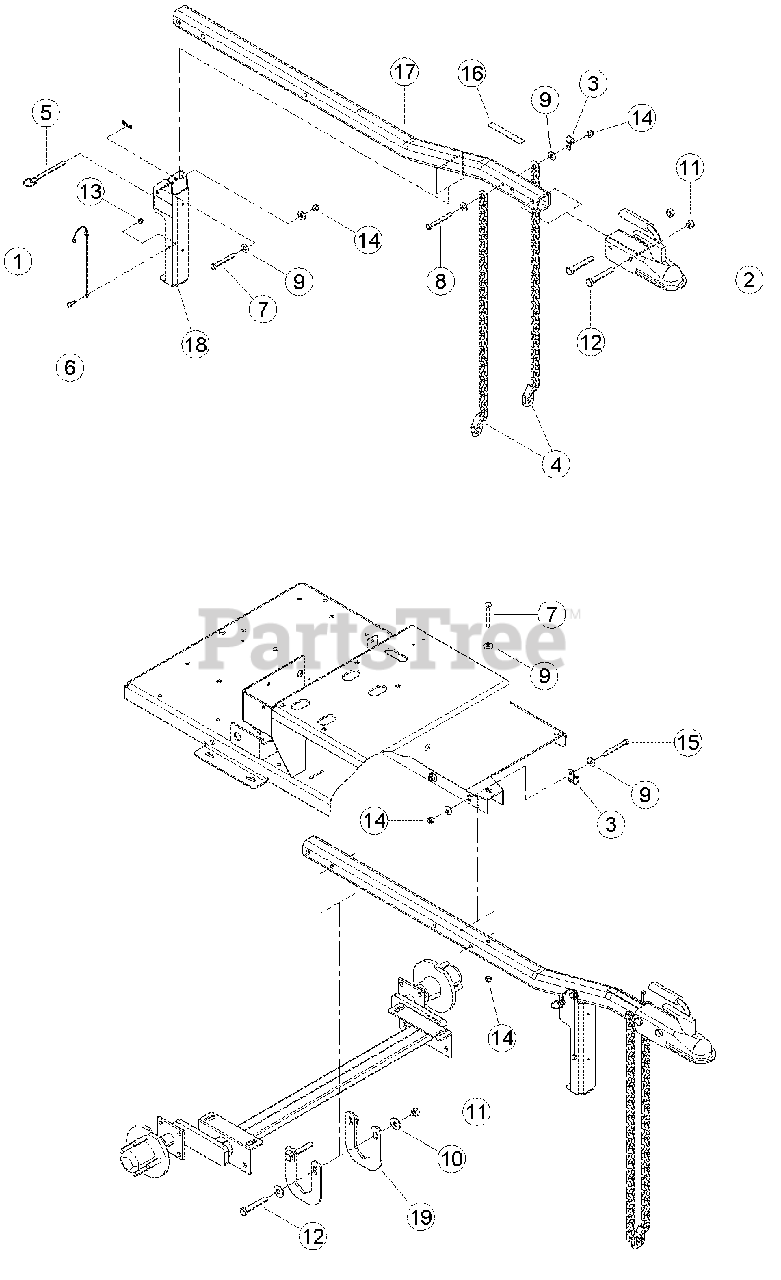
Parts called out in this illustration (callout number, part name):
1	LANYARD, NYLON
2	COUPLER, 50 MM BALL
3	CLAMP, 9/16" COATED
4	CHAIN, SAFETY 5000 LB W/LATCH
5	PIN, 3/8 HITCH
6	BOLT, 1/4 X 3/4 HEX HD GR5 ZP
7	BOLT, 3/8 X 3 HEX HD GR5 ZP
8	BOLT, 3/8 X 3-1/2 HEX HD GR5 ZP
9	WASHER, 3/8 FLAT ZP
10	WASHER, 1/2 FLAT ZP
11	NUT, 1/2 CENTERLOCK GRB ZP
12	BOLT, 1/2 X 3-1/4 HCS GR5 ZP
13	NUT, 1/4 NE NYLOCK ZP
14	NUT, 3/8 NE NYLOCK ZP
15	BOLT, 3/8 X 3-1/4 HEX HD GR5 ZP
16	DECAL, HITCH LOAD
17	POLE, C/S HITCH
18	STAND, JACK
19	PLATE, HITCH
